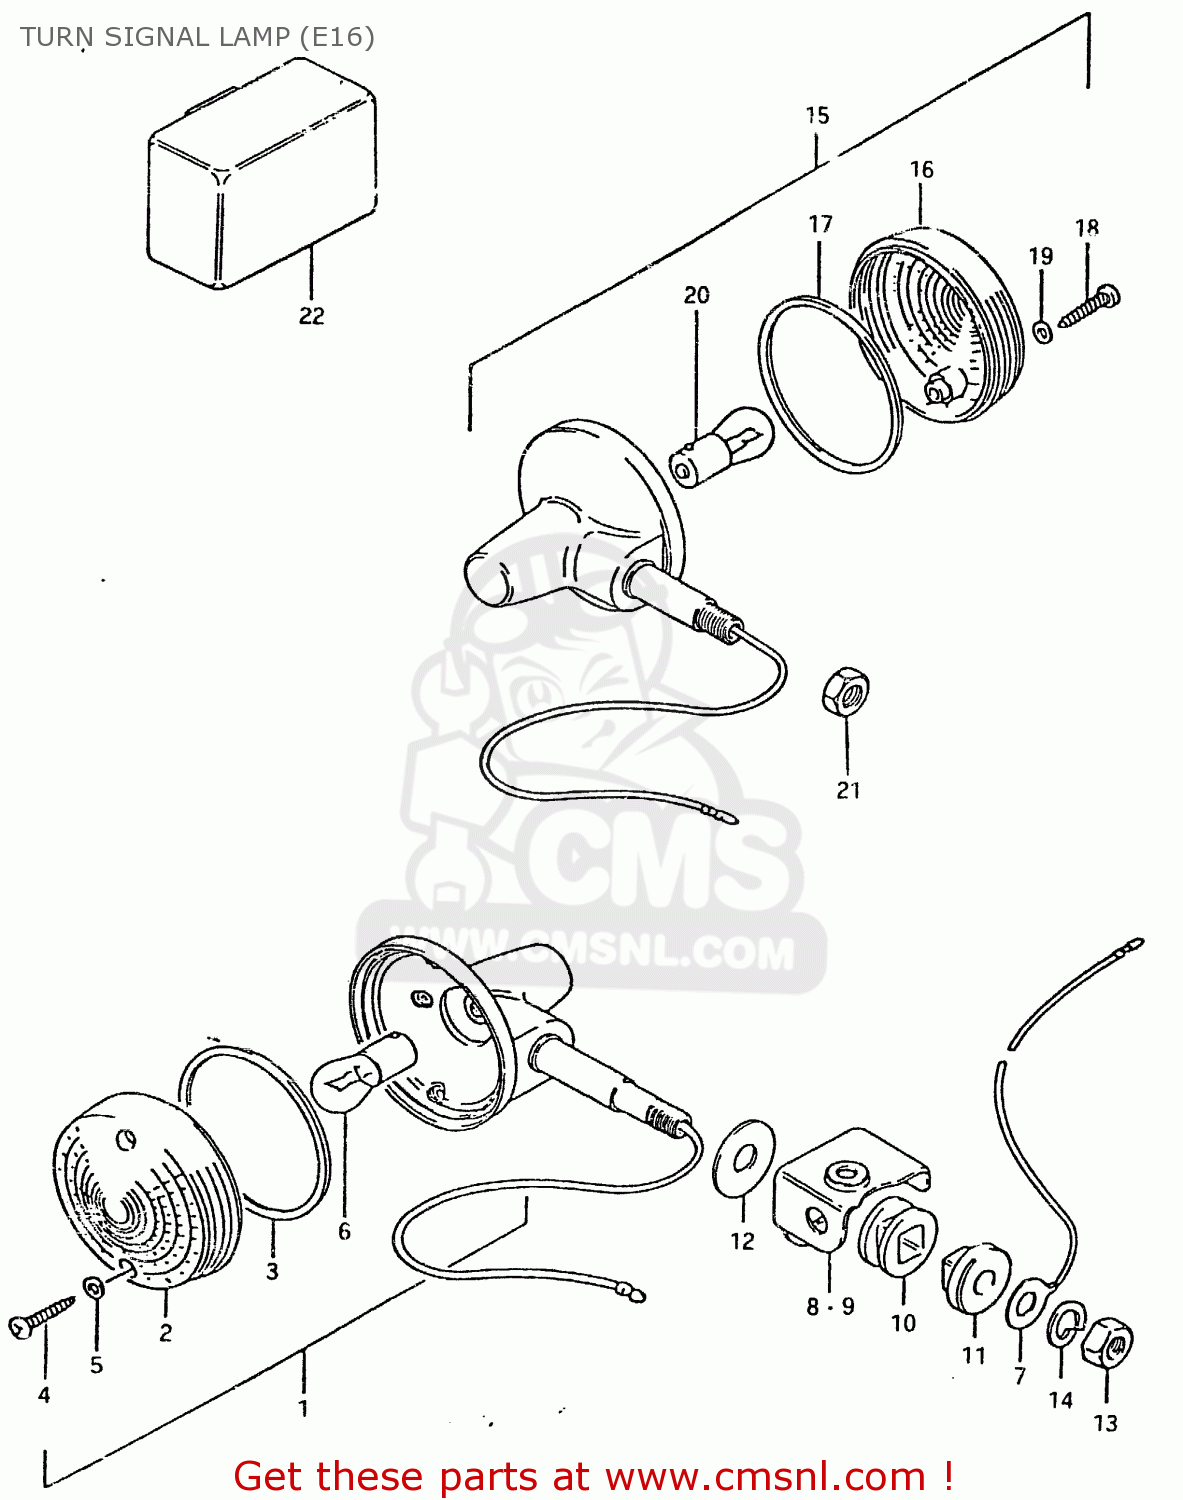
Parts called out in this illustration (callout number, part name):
1	LAMP ASSY,RR TURNSIGNAL
2	LENS
3	GASKET (NAS)
4	SCREW
5	GASKET (NAS)
6	BULB(6V/10W,STANLEY,A4117)
7	LEAD WIRE,EARTH
8	BRACKET,TURNSIGNAL LAMP,R
9	BRACKET,TURNSIGNAL LAMP,L
10	CUSHION
11	SPACER,RR TURNSIGNAL LAMP
12	WASHER (10.5X30X2.3)
13	NUT
14	LOCK WASHER
15	LAMP ASSY,RR TURNSIGNAL
16	LENS
17	GASKET (NAS)
18	SCREW
19	GASKET (NAS)
20	BULB(6V/10W,STANLEY,A4117)
21	NUT
22	RELAY, TURN SIGNAL
